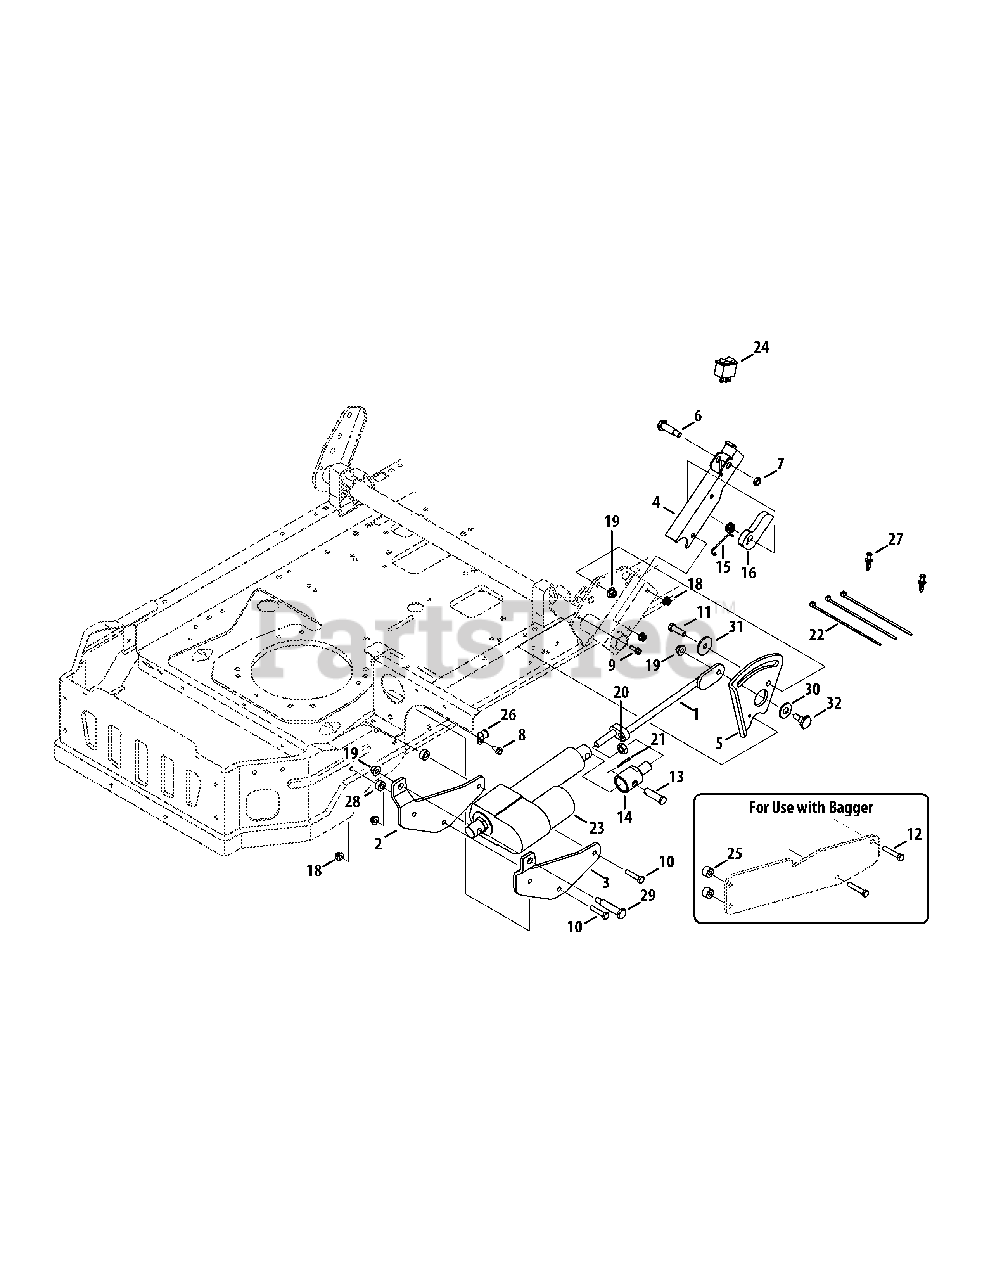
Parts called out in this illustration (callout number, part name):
1	Link Assembly, Lift
2	Bracket, Mounting, Inner
3	Bracket, Mounting, Outer
4	Handle, Lift, Electric
5	Bracket, Lift, Electric, RH
6	Screw, Shoulder, .50 x 1.25 x 3/8-16
7	Lock Nut, Jam, 3/8-16
8	Screw, Self-tapping, 5/16-18, .750
9	Screw, Self-tapping, 1/4-20, .750
10	Hex Screw, 5/16-18, 1.50
11	Hex Screw, 3/8-16, 1.25
12	Hex Screw, 5/16-18, 1.75
13	Pin, Clevis, .50 Dia x 1.59
14	Coupling, Lift, Actuator
15	Torsion Spring
18	Nut, Flange Lock, 5/16-18, Nylon
19	Nut, Flange Lock, 3/8-16, Nylon
20	Nut, Jam, 1/2-13, Gr5
21	Pin, Cotter, 1/8 x 1.0
22	Cable Tie, 7.4
25	Spacer, .325 x .75 x .520
27	Rivet, Plastic
28	Spacer, .315 x .75 x .375
29	Screw, Shoulder, .498 x 2.045
30	Washer, Flat, .531 x 1.25 x .100
31	Washer, Flat, .390 x 1.50 x .134
32	Screw, Shoulder, .500 x .434
